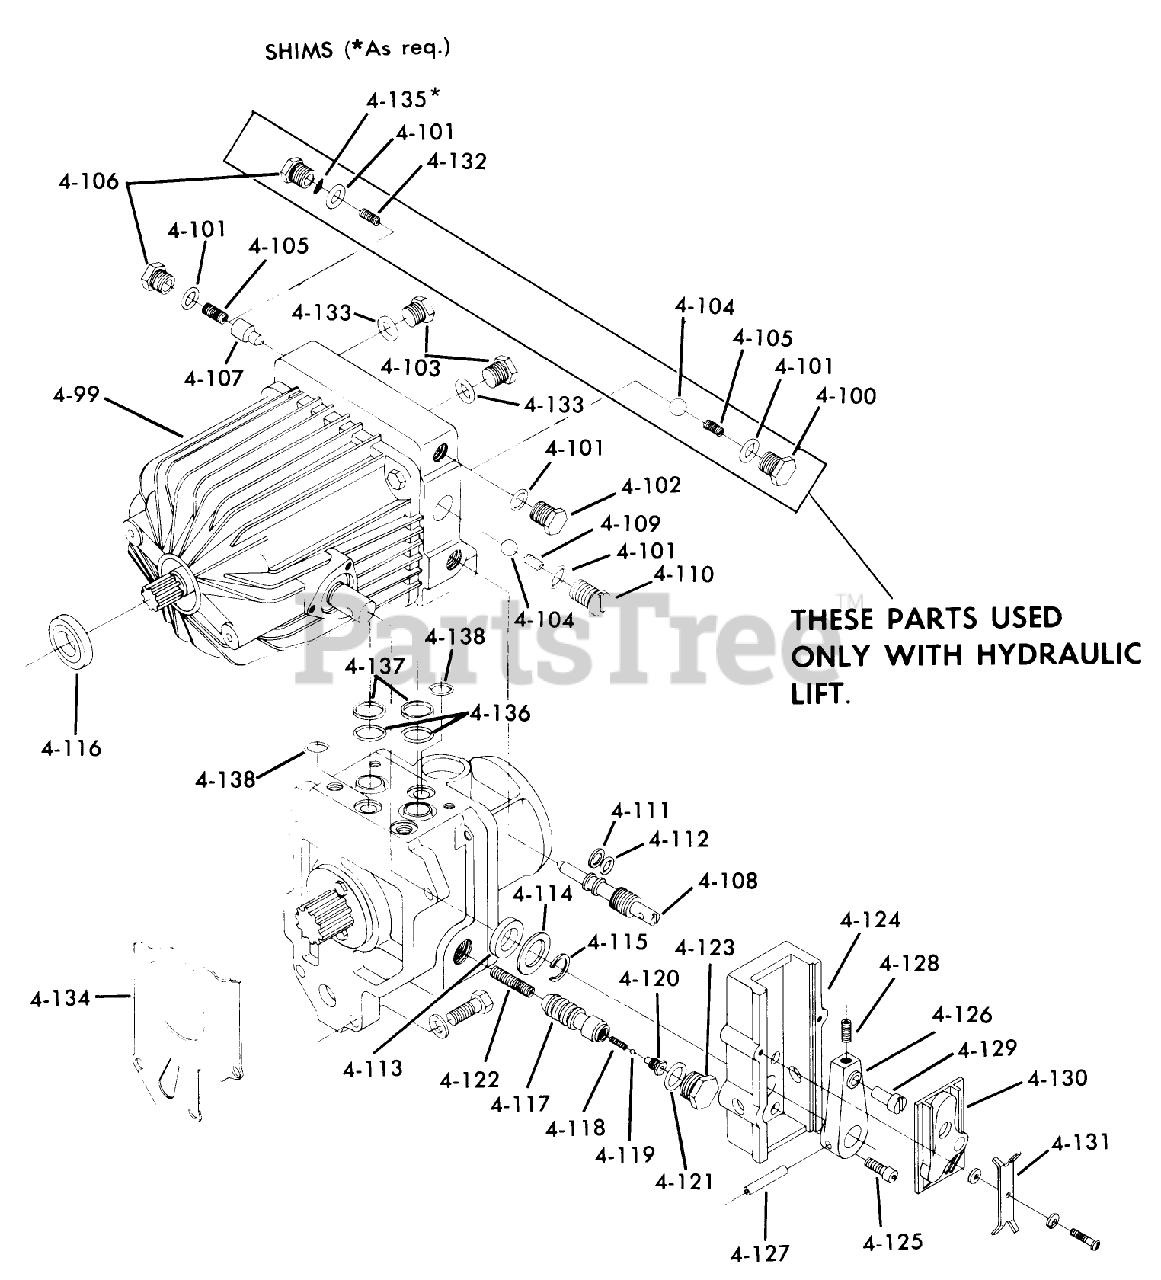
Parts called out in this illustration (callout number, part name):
4-99	SRV.BULLT 437B
4-99	SRV BULLT 437B
4-101	O RING
4-111	O-RING
4-130	CAM
4-134	GASKET
4-136	O RING
4-137	RING BACKUP
4-138	O RING
